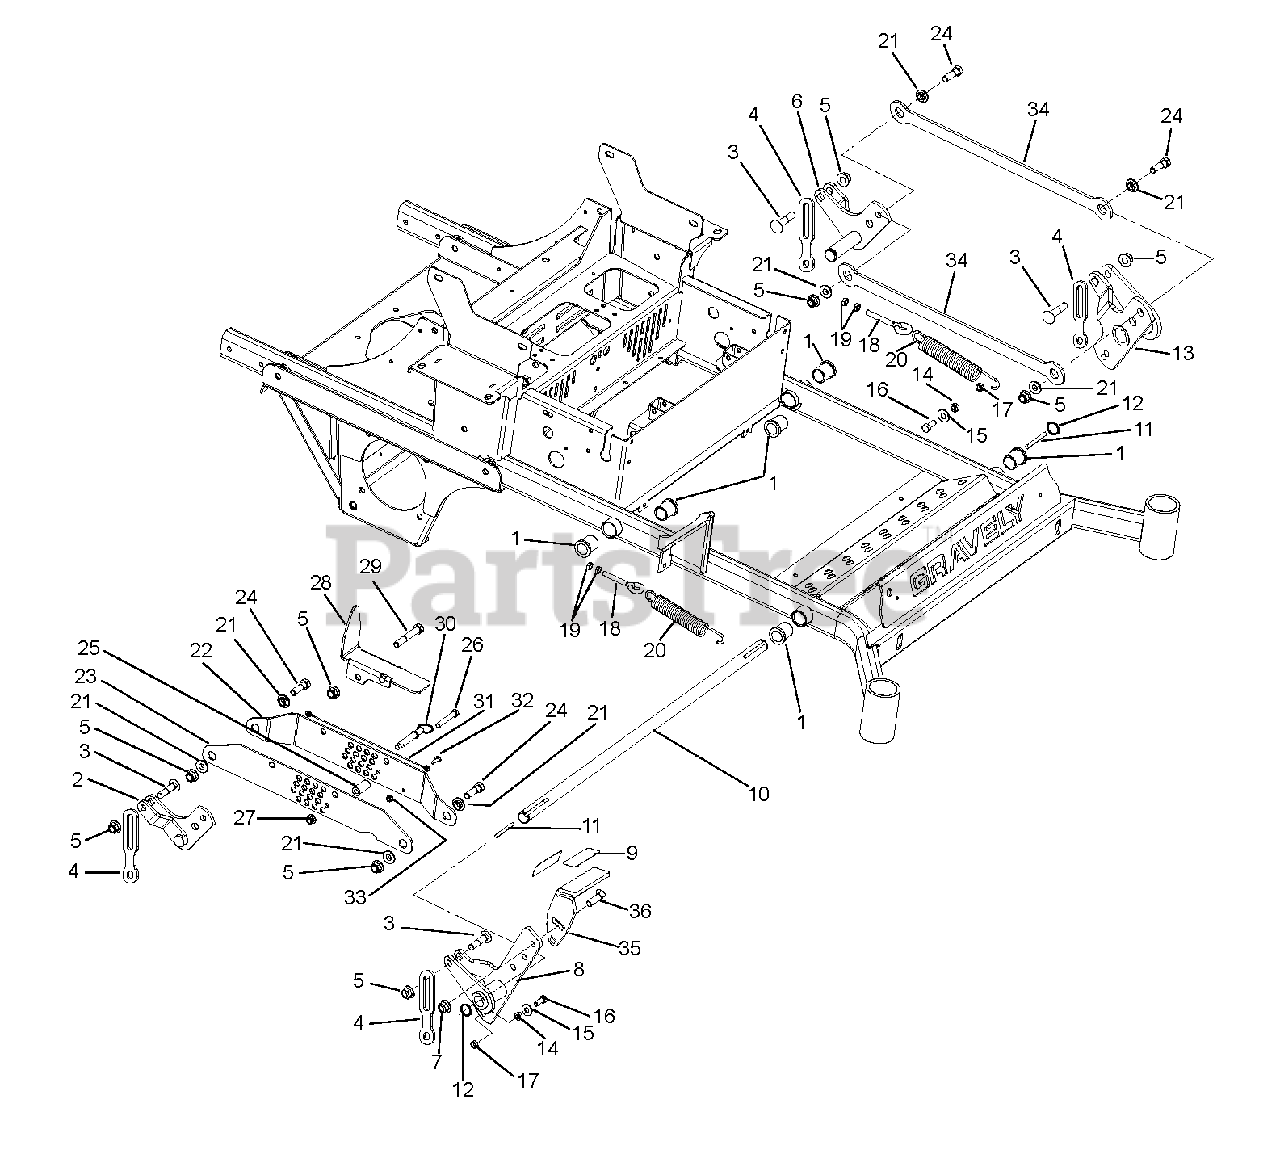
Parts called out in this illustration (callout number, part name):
1	Bushing, Flange 1.00 x 1.25 x 1.50 x 1.50
2	Weldment, Right Hand Rear Deck Lift
3	Bolt, Round Head Square Neck .50-13 x 2.25 G5YZ
4	Link, Deck Lift
5	Nut, Locking Nylon Flange .50-13
6	Weldment, Left Hand Rear Deck Lift
7	Nut, Locking Nylon Flange .50-13
8	Weldment, Adjustable Deck Foot Lift
9	Grip Pedal 1.50 x 3.00
10	Shaft, Front Mower Lift
11	Key, Square .25 x 2.50 x .25 SAE
12	Ring, Retaining External 1.00 x .078
13	Weldment, Front Left Hand Deck Lift
14	Bushing, Sleave .377 x .624 x .235
15	Washer, Flat Steel .438 x 1.00 x .083
16	Bolt, Hex .38-16 x 1.00 GR5
17	Nut, Locking Center Jam .375-16
18	Bolt, Eye .375-16 x 2.50
19	Nut, Hex Jam .375-16
20	Spring, Tension .162 x 1.25 x 8.25 WLD 25
21	Bushing, Flange .515 x .750 x .395 x 1.120
22	Bracket, Right Hand Lift/Cut Height Inboard
23	Bracket, Right Hand Lift/Cut Height Outboard
24	Bolt, Hex .50-13 x 1.75 GR5
25	Spacer, .375 x .750 x 1.54
26	Bolt, Hex .38-16 x 2.50 GR5
27	Nut, Locking Nylon Flange .38-16
28	Weldment, Mechnical Lock-Up
29	Bolt, Hex .50-13 x 3.25 GR5
30	Pin, .50 x 2.00
31	Cable, 12.0 Lanyard, Nylon
32	Bolt, Hex .25-20 x .75 GR5
33	Nut, Locking Nylon Flange .25-20
34	Link, Lift
35	Adjustable Foot Lift Pedal, Black
36	Bolt, Round Head Square Neck .50 x 13 x 1.50 Grade 5 YZ
